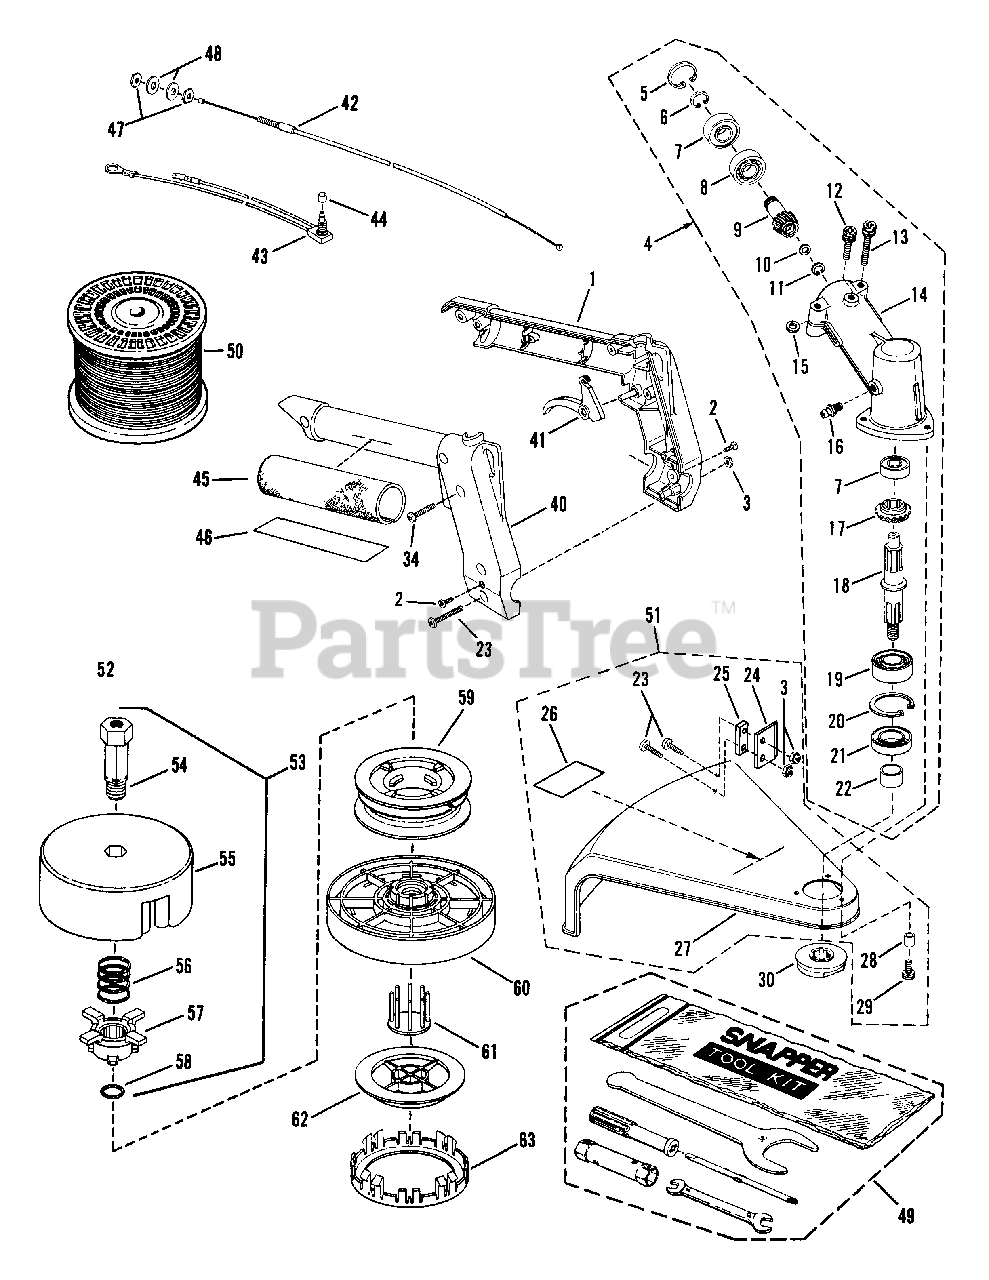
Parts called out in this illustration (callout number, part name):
1	HANDLE, Left Half
2	SCREW, TORX, #6 X 5/16
3	LOCKNUT, #10-32
4	GEAR HEAD ASSM'Y
5	SNAP RING, 26mm
6	SNAP RING, 10mm
7	BEARING
8	BEARING
9	BEVEL PINION
10	WASHER, Flat
11	SNAP RING, 10mm
12	BOLT, M5 x 12mm Hex Head
13	BOLT, M5 x 25mm Hex Head
14	GEAR CASE
16	FITTING, Lube
17	BEVEL GEAR
18	SPLINE SHAFT
19	BEARING
20	SNAP RING, 35mm
21	SEAL, Oil
22	SPLINE SLEEVE
23	SCREW, #10-32 x 7/8"
24	CUTTER ASSM'Y., Line
25	BLOCK, Line Cutter Mounting
26	LABEL, Replacement Part
27	SHIELD ASSM'Y.
29	BOLT, M5 x 16mm
34	Screw, #10-32 x 7/8"
40	HANDLE, Right Half
41	TRIGGER
42	CABLE, Throttle
43	SWITCH
44	CAP, Switch
45	GRIP, Handle
46	STRIP, Adhesive
47	NUT, M6 Hex
49	TOOL KIT
50	SPOOL, 50ft. Mono Line (.080 Dia.)
51	KIT, Plastic Shield
52	ASSM'Y.,Tap Head, Left Hand
53	ASSM'Y, Housing
55	HOUSING
57	INDEXER
58	RETAINER, Wire
61	ACTUATOR
63	RETAINER, Knob
